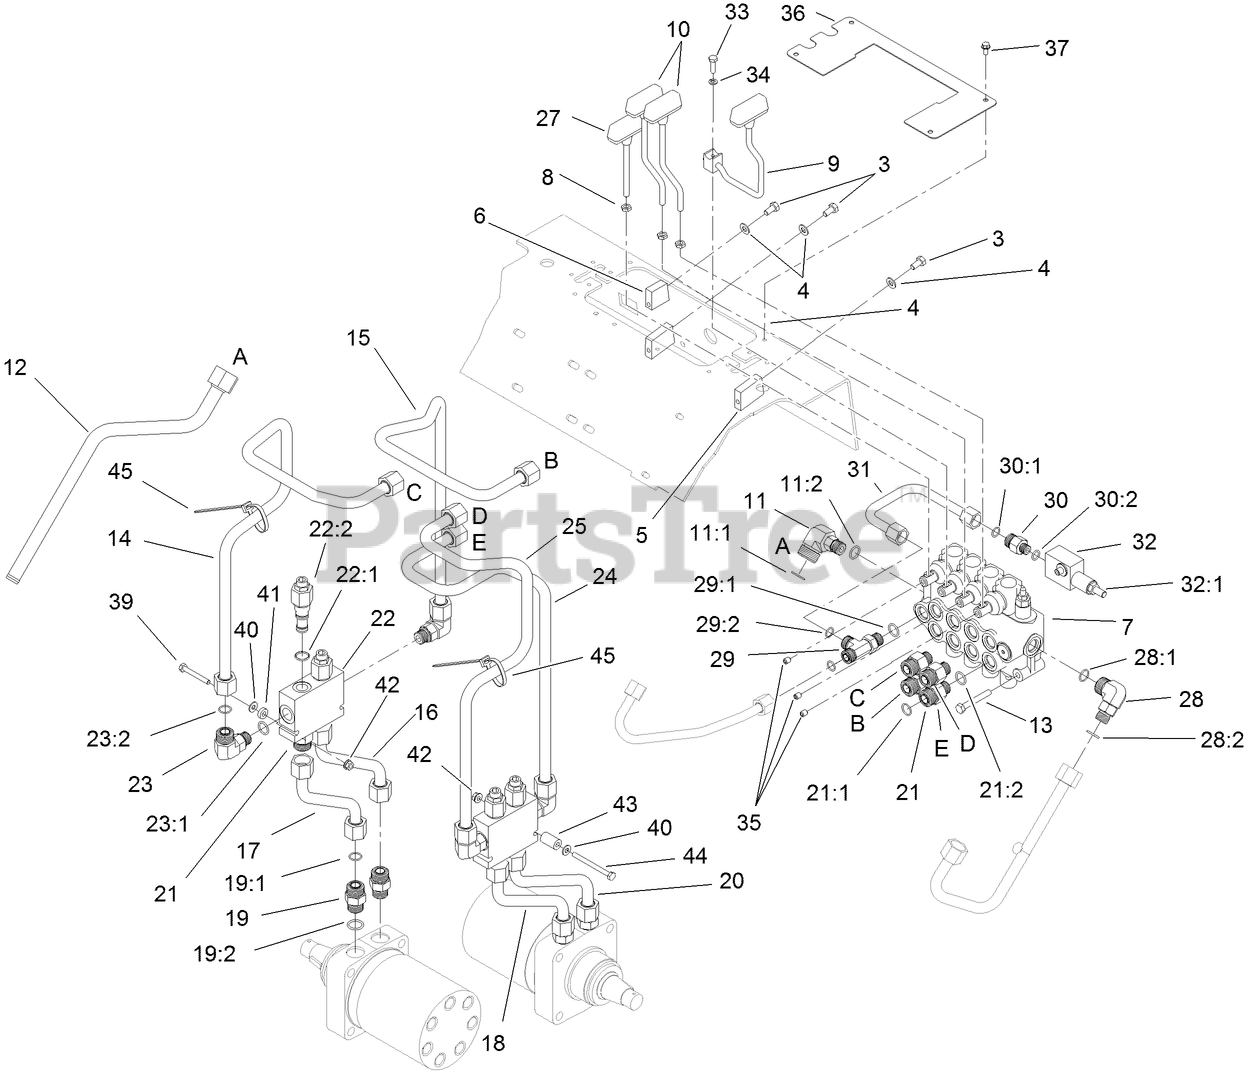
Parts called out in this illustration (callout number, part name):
3	SCREW-HH
4	WASHER-PLAIN
5	SPACER
6	SPACER-UPPER
7	VALVE-FOUR SPOOL (W/ RELIEF PORT)
8	NUT-HEX
9	LEVER-CONTROL
10	LEVER-DRIVE
11	FITTING-HYD, 90 DEG
11:1	O-RING
11:2	O-RING
12	TUBE-TANK, HYD
13	SCREW-HH
14	TUBE-HYD (RIGHT B)
15	TUBE-HYD (RIGHT A)
16	TUBE-HYD
17	TUBE-HYD
18	TUBE-HYD
19	FITTING-STRAIGHT
19:1	O-RING
19:2	O-RING
20	TUBE-HYD
21	FITTING-STR
21:1	O-RING
21:2	O-RING
22	VALVE-COUNTERBALANCE
22:1	SEAL KIT
22:2	VALVE-CARTRIDGE
23	Fitting-Elbow, 90 DEG
23:1	O-RING
23:2	O-RING
24	TUBE-HYD (LEFT A)
25	TUBE-HYD (LEFT B)
27	LEVER-CYLINDER
28	Fitting-Elbow, 90 DEG
28:1	O-RING
28:2	O-RING
29	FITTING-TEE
29:1	O-RING
29:2	O-RING
30	FITTING-STR
30:1	O-RING
30:2	O-RING
31	TUBE-HYD
32	RELIEF VALVE ASM
32:1	CARTRIDGE-VALVE, RELIEF
33	SCREW-HH
34	WASHER-LOCK
35	SCREW-SET, HSH
36	PLATE-COVER
37	SCREW-HWH
39	SCREW-HH
40	WASHER-FLAT
41	SPACER
42	NUT-HHF
43	SPACER
44	SCREW-HH
45	TIE-CABLE
